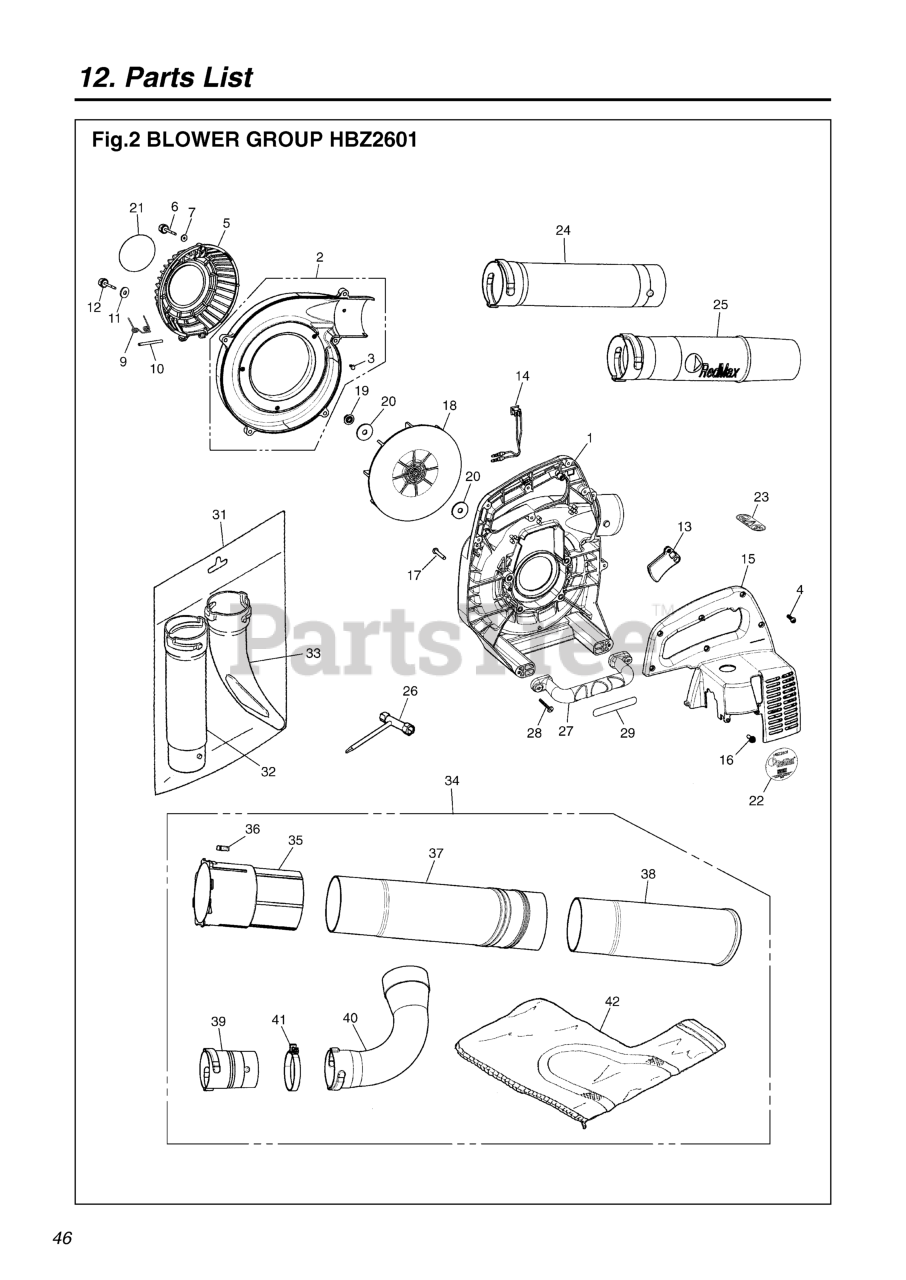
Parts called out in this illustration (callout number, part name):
1	VOLUTE CASE (RPLS. 6811-11110)
2	VOLUTE COVER (HBZ2600)
3	SCREW
4	SCREW, TORX (RPLS T4970-52001)
5	GUARD NET
6	SCREW
7	WASHER
9	SPRING
10	SHAFT
13	LEVER
14	SWITCH
15	ENGINE COVER
16	BOLT
17	SCREW
18	FAN
20	WASHER
21	LABEL, CAUTION
22	LABEL, RECOIL
23	LABEL, CE CAUTION
24	PIPE, STRAIGHT
25	PIPE, END
27	HANDLE
28	SCREW
31	FLAT NOZZLE SET
32	PIPE, STRAIGHT
33	NOZZLE, FLAT
34	VACUUM KIT
35	PIPE, A
37	PIPE, B
38	PIPE, C
39	EXTENSION (PIPE)
40	ELBOW
41	CLAMP
42	BAG, DUST
